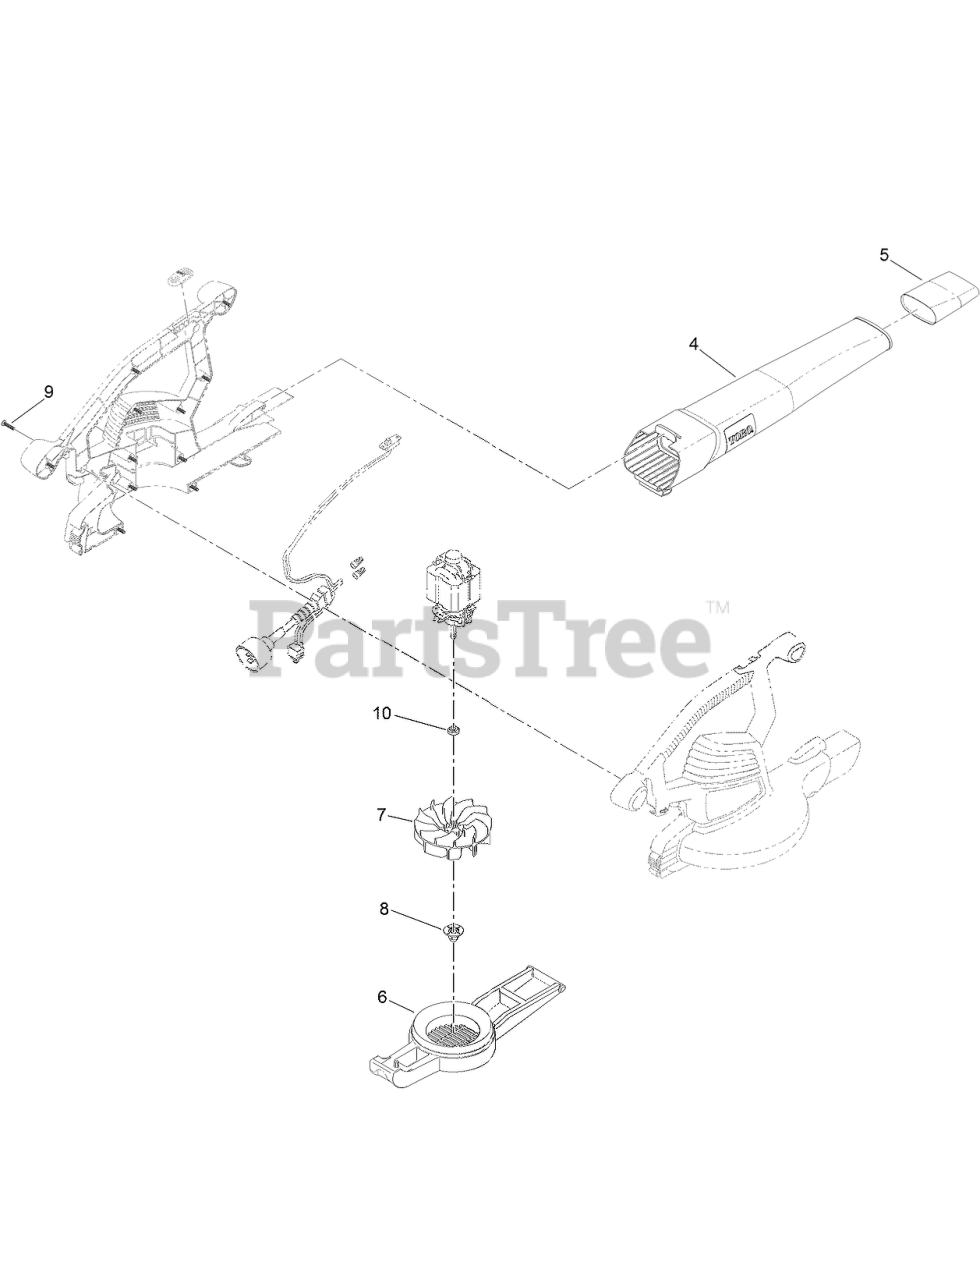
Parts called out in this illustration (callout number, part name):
4	TUBE-BLOWER
5	TUBE-INSERT, SUPER
6	COVER-INLET
7	IMPELLER
8	NUT-IMPELLER
9	SCREW-PPH
10	BUSHING-MOTOR
